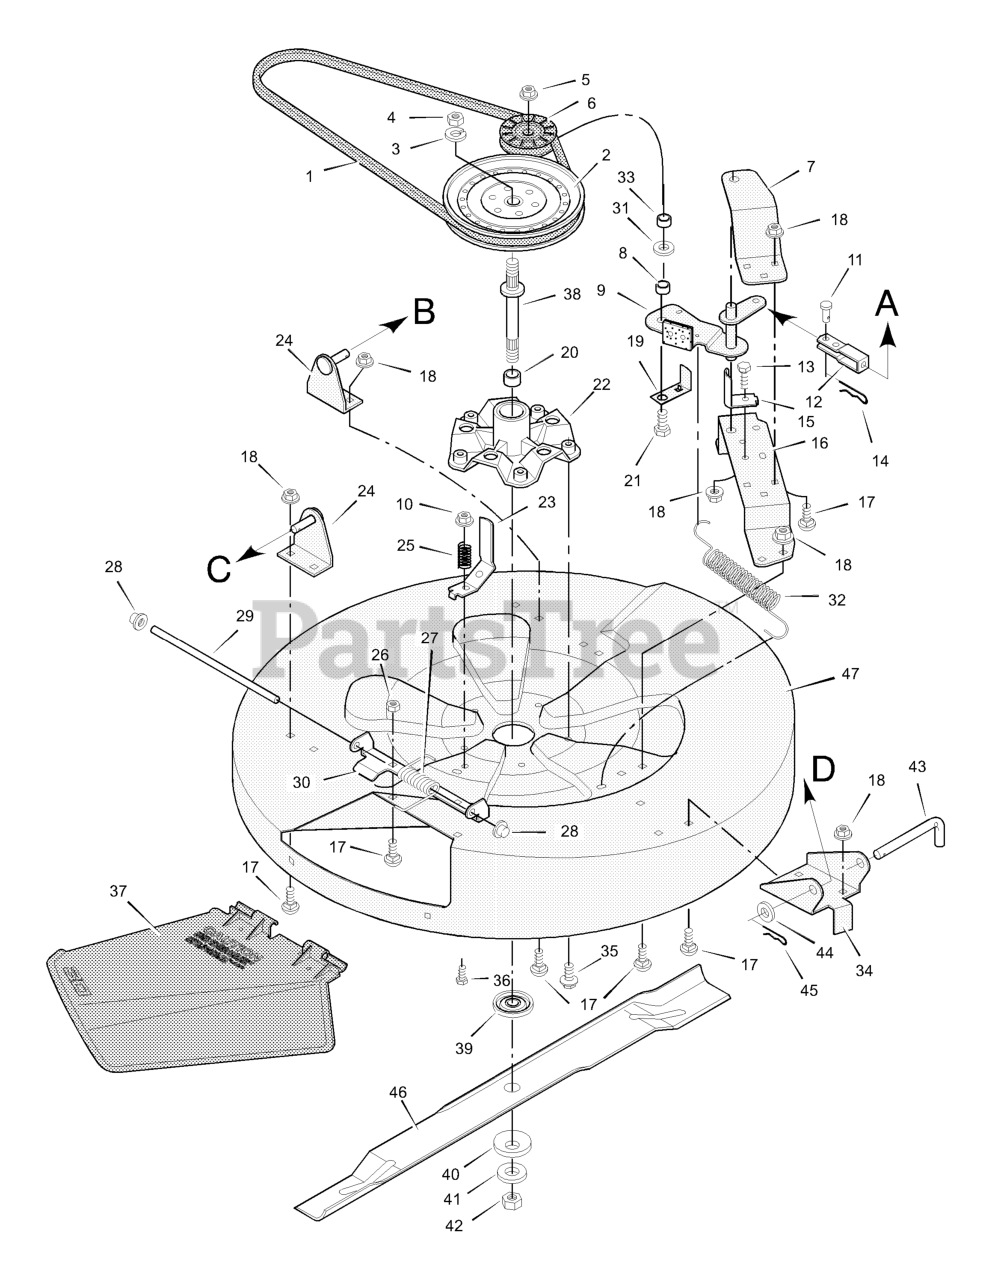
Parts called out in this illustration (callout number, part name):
1	Belt, Mower Drive
2	Pulley, Splined
3	Lockwasher
4	Locknut, Hex
5	Nut, Hex
6	Pulley, Idler
7	Bracket, Upper Idler
9	Assembly, Blade Idler
10	Locknut, Flange
11	Pin, Clevis
13	Bolt, Hex
14	Pin, Hair
15	Guide, Belt
16	Bracket, Lower Idler
17	Bolt, Carriage
18	Nut, Flange
19	Guide, Belt
21	Bolt, Hex
22	Housing, Mandrel
23	Guide, Belt
24	Bracket, Hanger
25	Spring, Compression
26	Nut, Hex
27	Spring - Torsional
28	Push On Cap
30	Hinge, Chute Deflector
32	Spring, Extension
34	Bracket, Front
36	Bolt, Hex
37	Deflector, Chute
38	Mandrel
39	Adapter, Blade
40	Washer, Belleville
41	Washer, Hardened
42	Nut, Hex
43	Pin, Pull
45	Pin, Hair
46	Blade, Standard
47	Mower Housing ONLY
